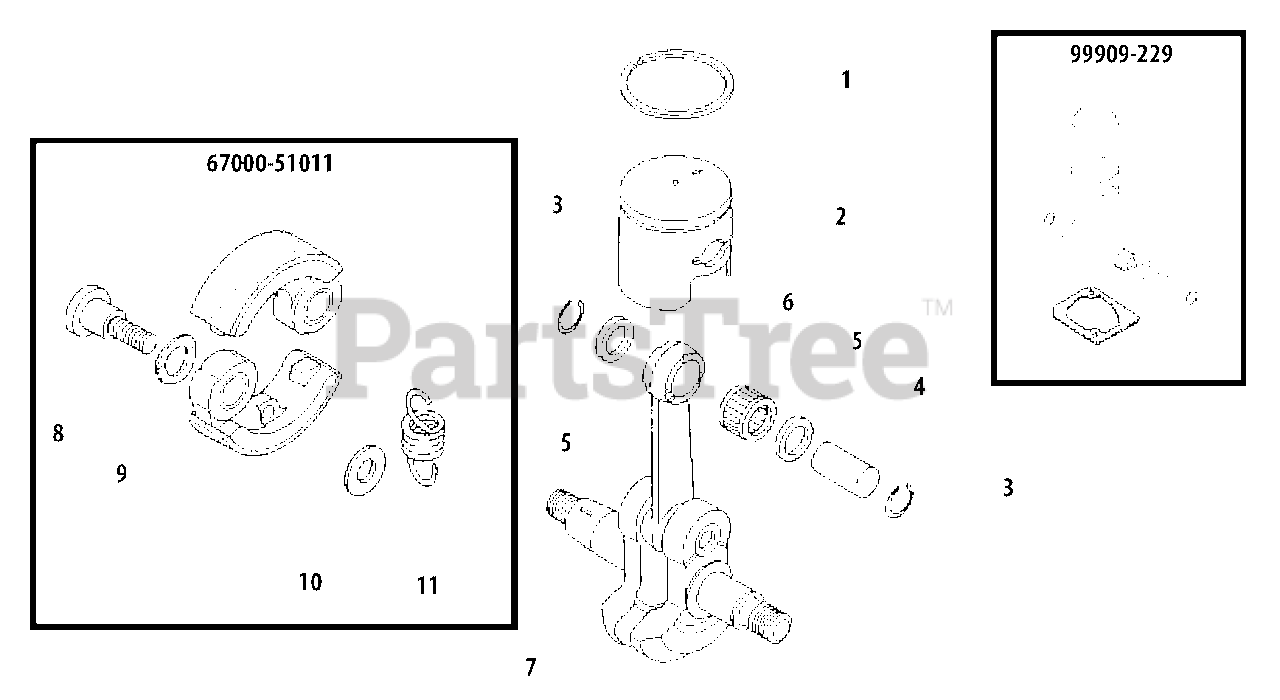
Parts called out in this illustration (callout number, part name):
1	RING, PISTON
2	PISTON
3	RING, RETAINING
4	PIN, PISTON
5	WASHER, THRUST
6	BEARING, NEEDLE
7	CRANKSHAFT ASSY
8	BOLT, CLUTCH
9	WASHER - SPRING
10	WASHER - 6
11	SPRING, CLUTCH
67000-51011	CLUTCH ASSY
99909-229	PISTON KIT
